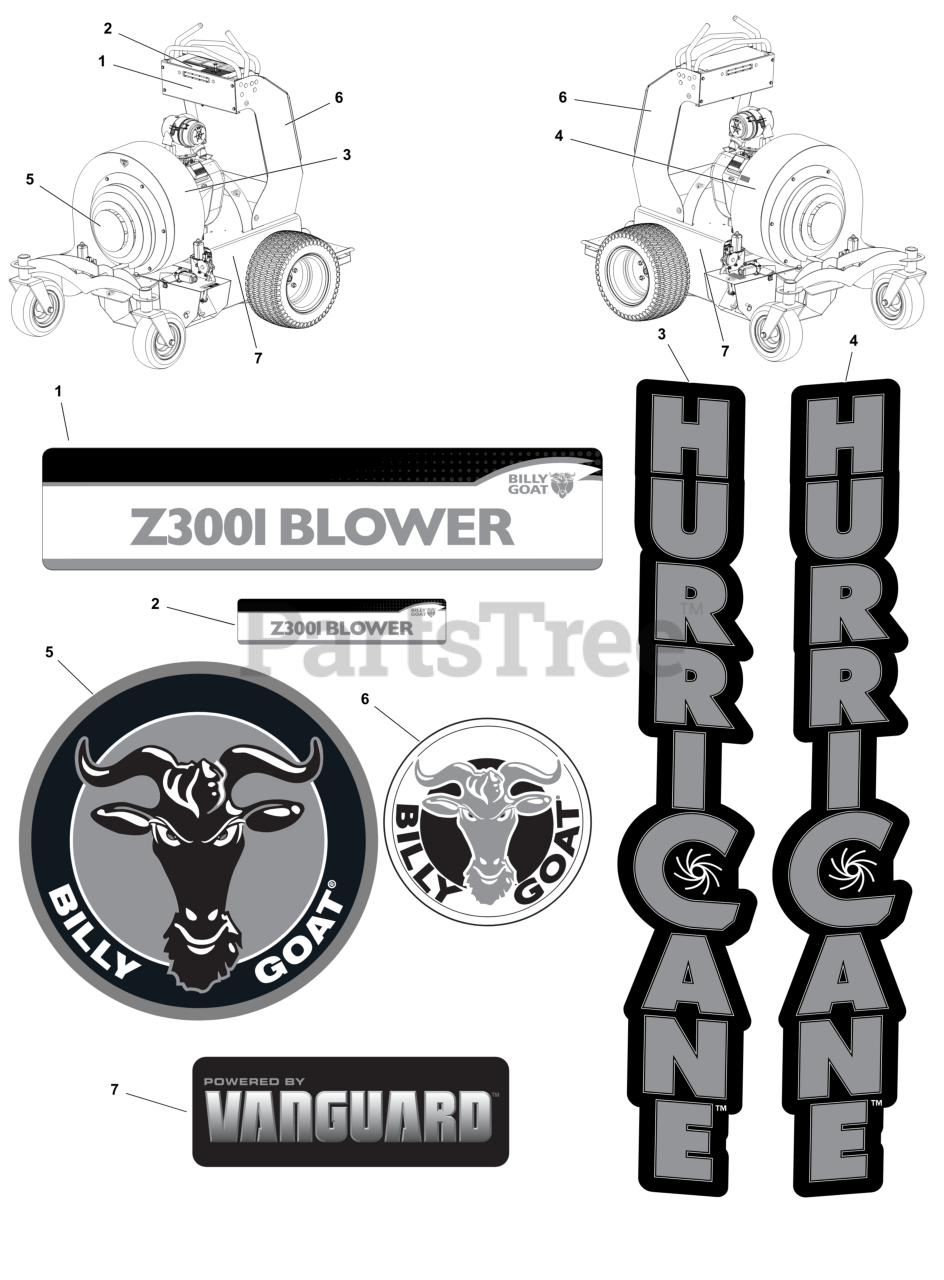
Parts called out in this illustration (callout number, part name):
1	DECAL, Z3001 BADGE, BG
2	DECAL, Z3001 TOP PANEL, BG
3	DECAL, Z3000 HURRICANE_VERT, BG,LH
4	DECAL, Z3000 HURRICANE_VERT, RH
5	DECAL, Z3000 FRONT LOGO
6	LABEL, PRODUCT DECAL LG CIRCLE
7	DECAL, BRAND
